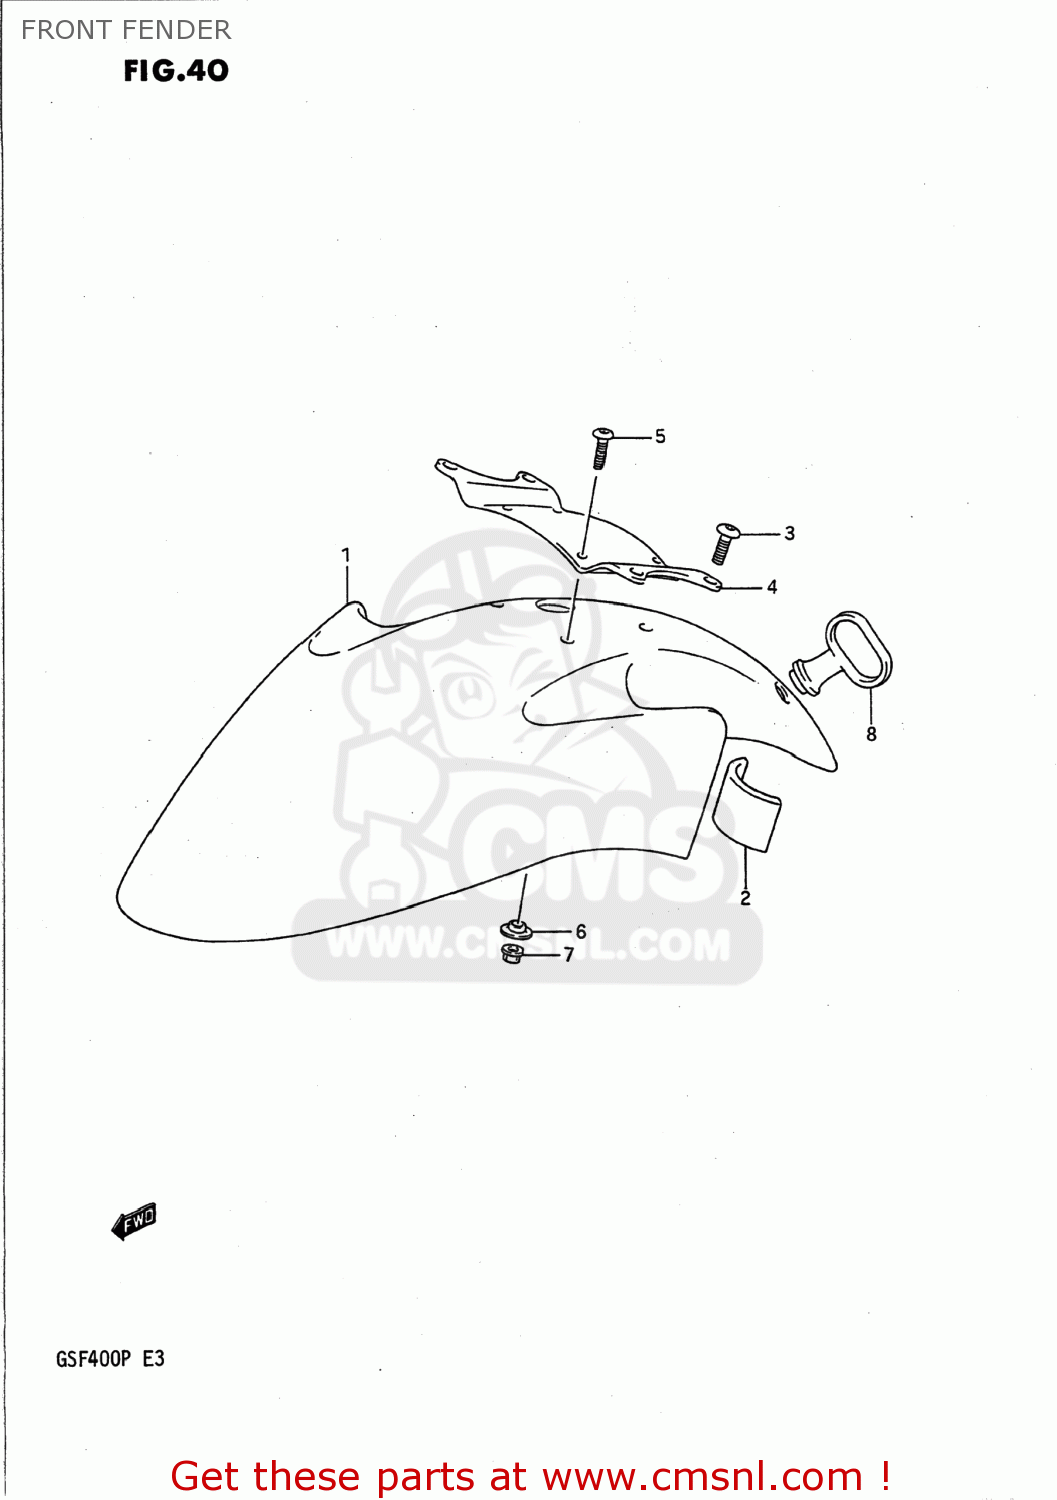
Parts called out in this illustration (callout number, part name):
1	FENDER,FR
2	CUSHION,FR FENDER
3	SCREW(6X12)
4	BRACE,FR FENDER
5	SCREW(5X16)
6	WASHER
7	NUT
8	GUIDE,CABLE
